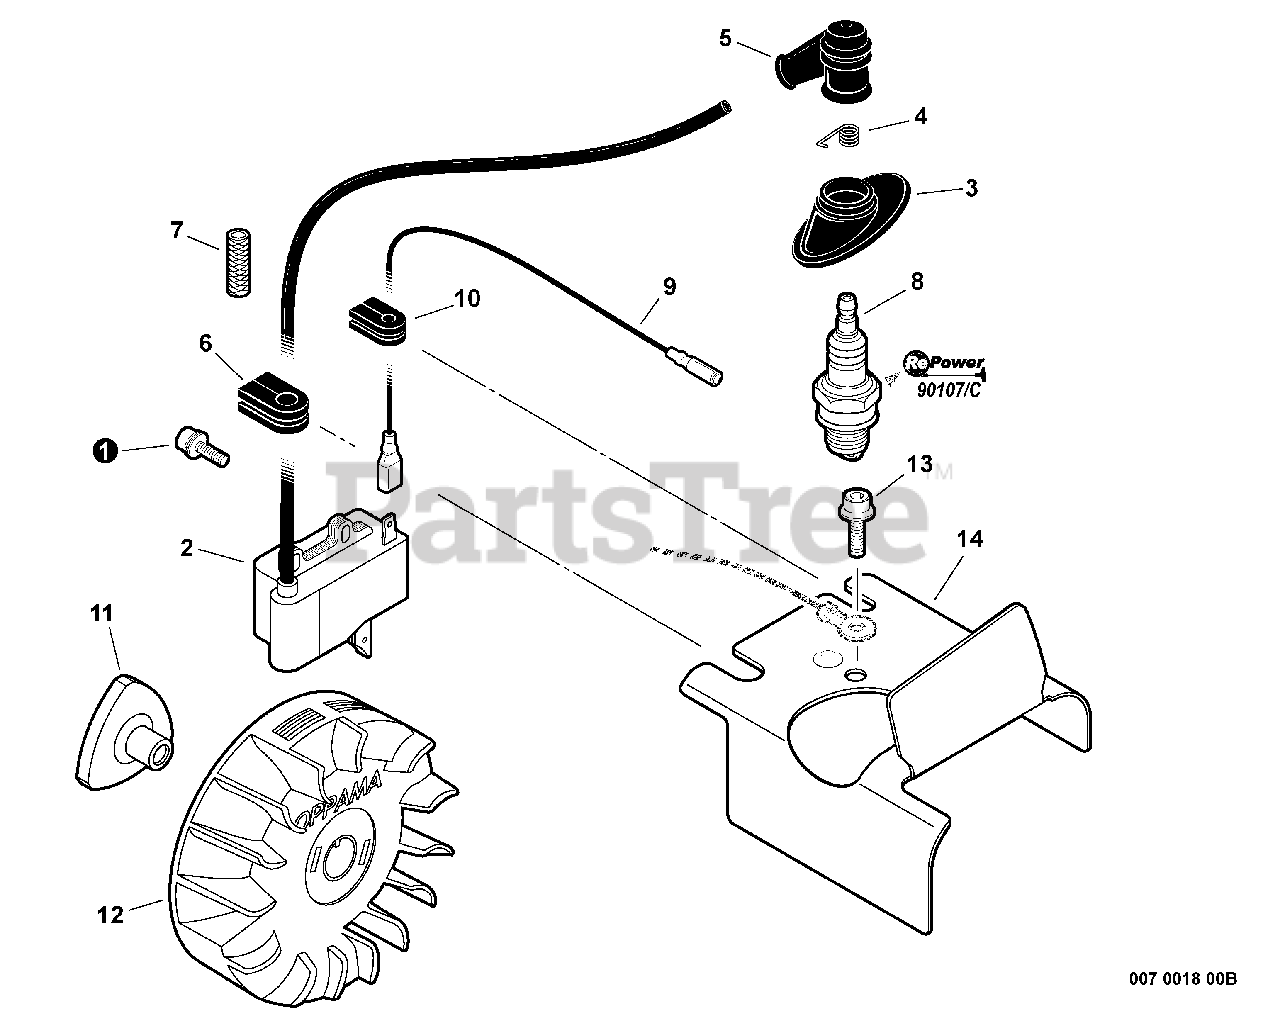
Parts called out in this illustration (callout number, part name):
1	SCREW - 4X20
2	COIL, IGNITION
3	COVER, DUST
4	TERMINAL, SPARK PLUG CAP
5	CAP, SPARK PLUG
7	INSULATOR
8	SPARK PLUG -- BPM-8Y
8	SPARK PLUG -- BPMR-8Y
9	LEAD - IGNITION
11	HUB, FAN
12	FLYWHEEL
13	SCREW - 5X8
14	SHIELD, CYLINDER
15	RePower TUNE-UP KIT
